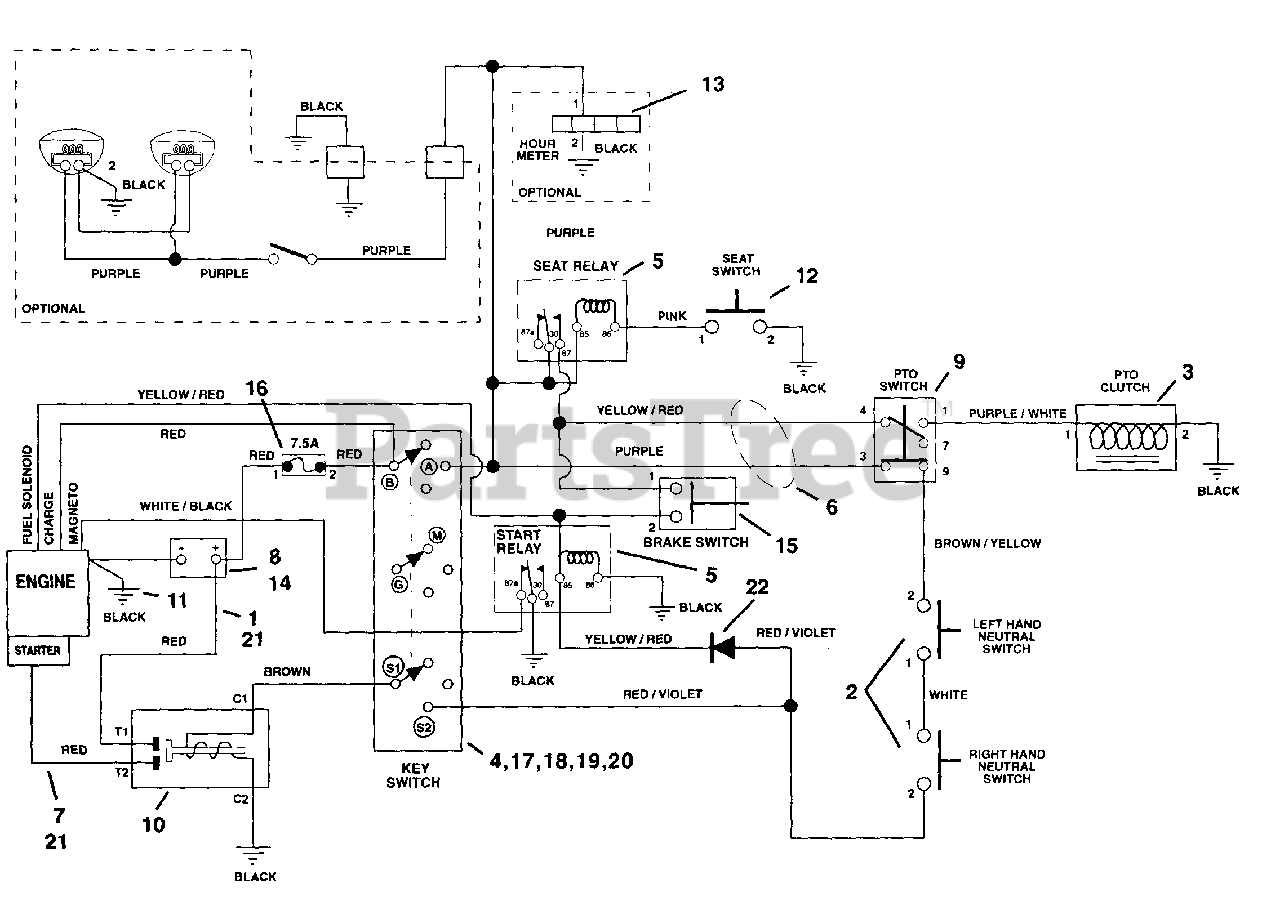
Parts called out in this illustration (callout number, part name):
1	CBL,BATTERY TO SOLENOID
2	SWITCH, NEUTRAL START N.O.
3	ELECTRIC CLUTCH/BRAKE(1.8AMP)
4	KEY SWITCH
5	RELAY
6	HARNESS, WIRE - 1440
7	STARTER CABLE 6.75"
8	BATTERY W/ TUBE
9	SWITCH, CLUTCH WITH RETAINER
10	SOLENOID
11	GROUND CABLE .31X22.00X.31
12	SWITCH- SEAT
13	HOUR METER
14	RUBBER PAD
15	SWITCH- SINGLE POLE N.O.
16	7.5 AMP Fuse
17	KEY -W/CAP
18	CAP - IGNITION SWITCH
19	NUT- PANEL .562-24 GRECO
20	WSHR-LK-INT .563X.040 PL
21	BOOT, INSULATOR
22	MOLDED DIODE PLUG 1 AMP
